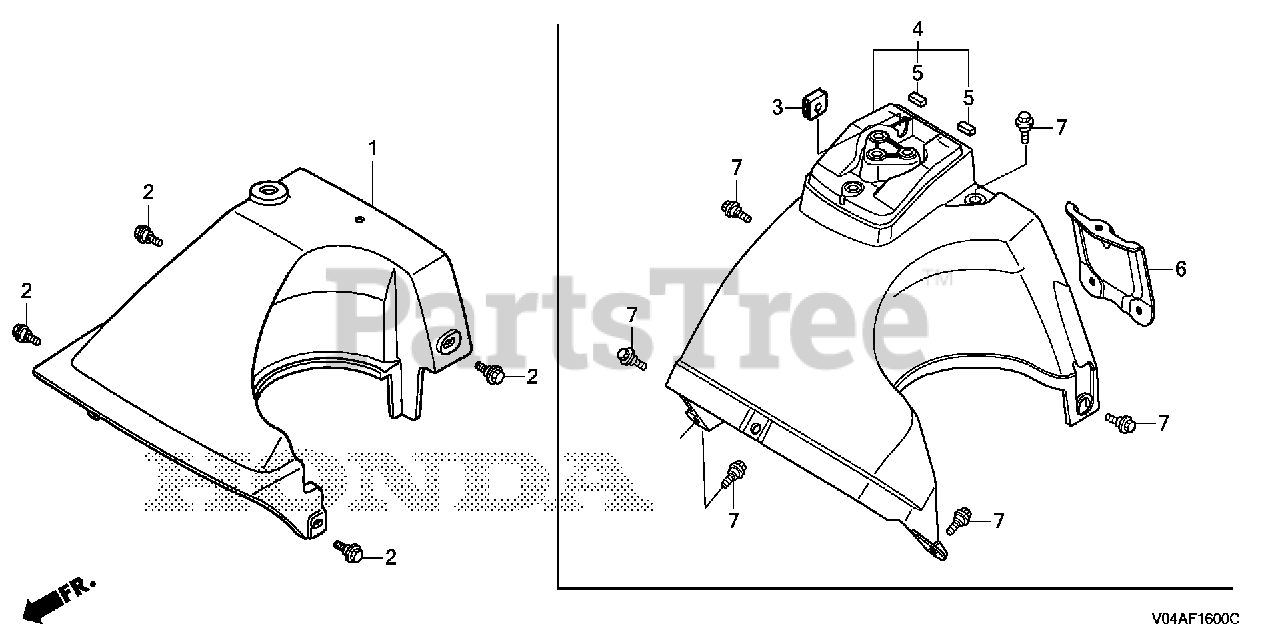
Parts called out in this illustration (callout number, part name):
3	GROMMET, WIRE
4	COVER, MOTOR *R280* (POWER RED)
5	RUBBER, COVER MOUNT
6	BRACKET B, MOTOR COVER
7	BOLT, FLANGE (6MM)
